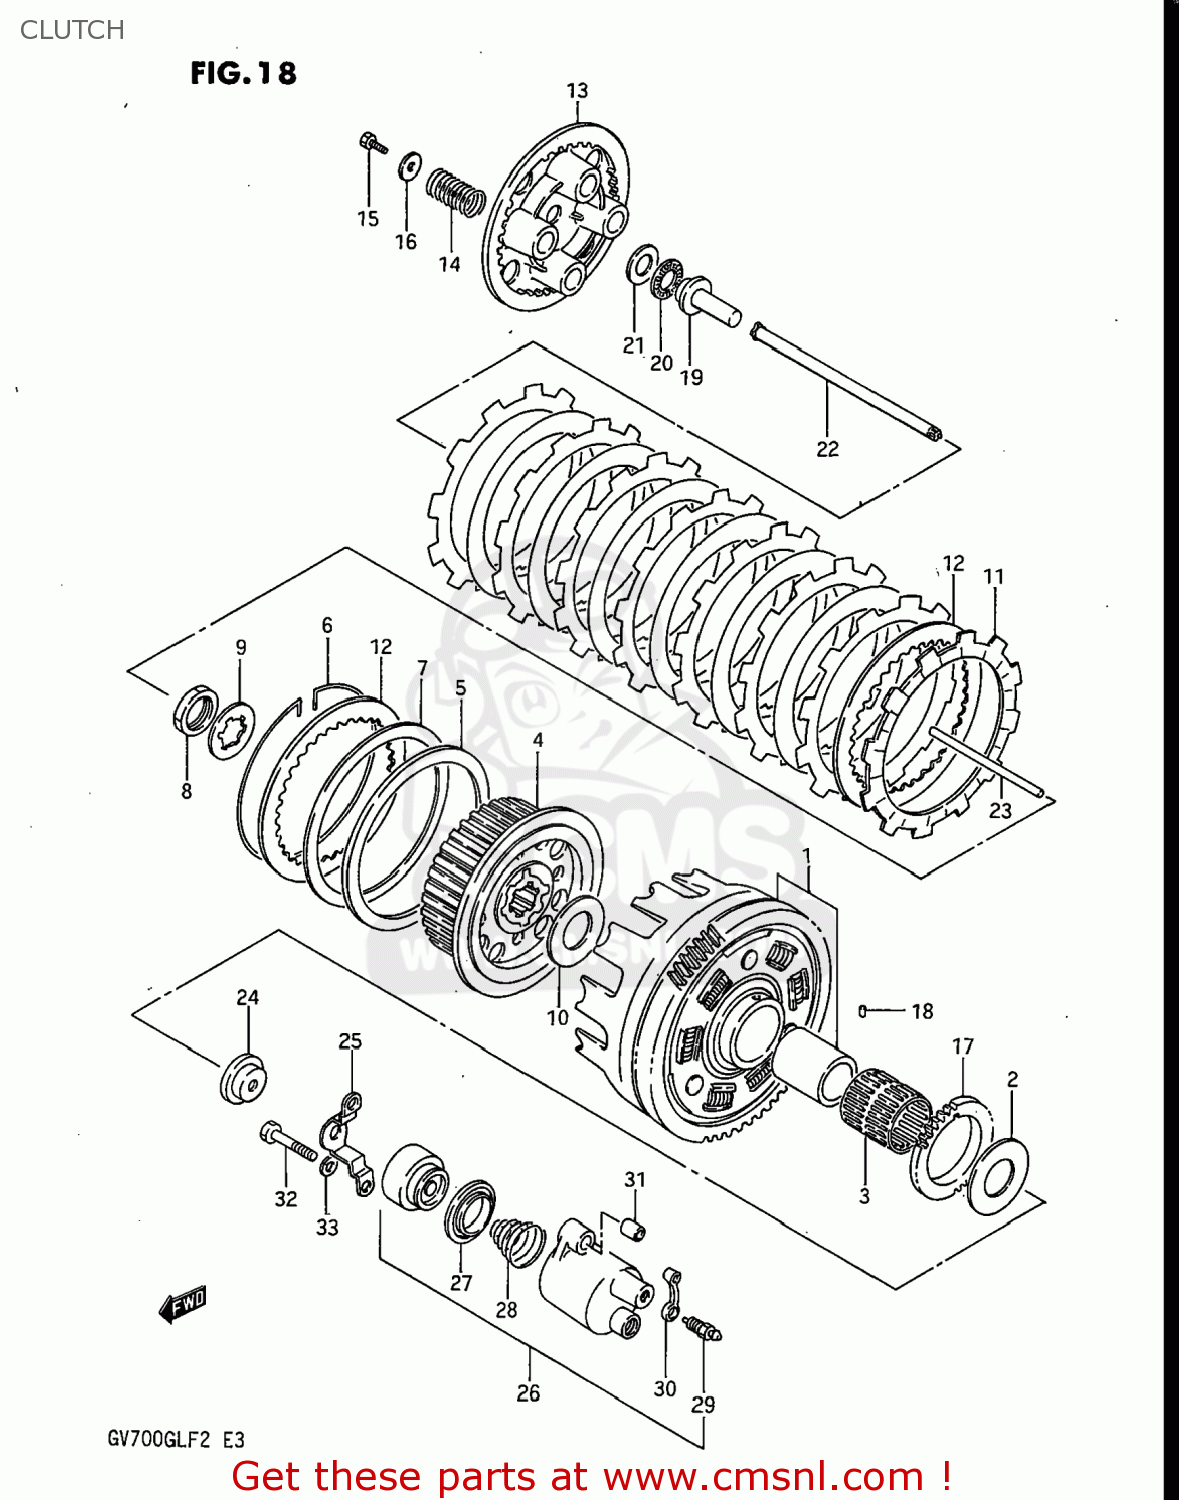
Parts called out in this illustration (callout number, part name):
1	GEAR ASSEMBLY,PRIMARY DRIVE
2	WASHER (25X54X2.5)
3	BEARING(35X40X39.8)
4	HUB,CLUTCH SLEEVE
5	SEAT,WAVE WASHER
6	RING,STOPPER
7	WASHER
8	NUT
9	WASHER,LOCK
10	WASHER(25X50X2.5)
11	PLATE,CLUTCH DRIVE
12	PLATE,CLUTCH DRIVEN(T:2.0) (NAS)
13	PLATE,CLUTCH PRESSURE
14	SPRING
15	BOLT, UPPER
16	WASHER
17	GEAR,OIL PUMP DRIVE
18	PIN(6X6)
19	PIECE,CLUTCH PUSH
20	BEARING(15X28X2)
21	WASHER
22	ROD,CLUTCH PUSH
23	ROD,CLUTCH PUSH
24	OIL SEAL
25	PLATE,CLUTCH PUSH ROD
26	CYLINDER,CLUTCH RELEASE
27	CUP,CLUTCH CYLINDER
28	SPRING,CLUTCH CYLINDER
29	BLEEDER
30	CAP,BLEEDER
31	PIN
32	BOLT ,6X35
